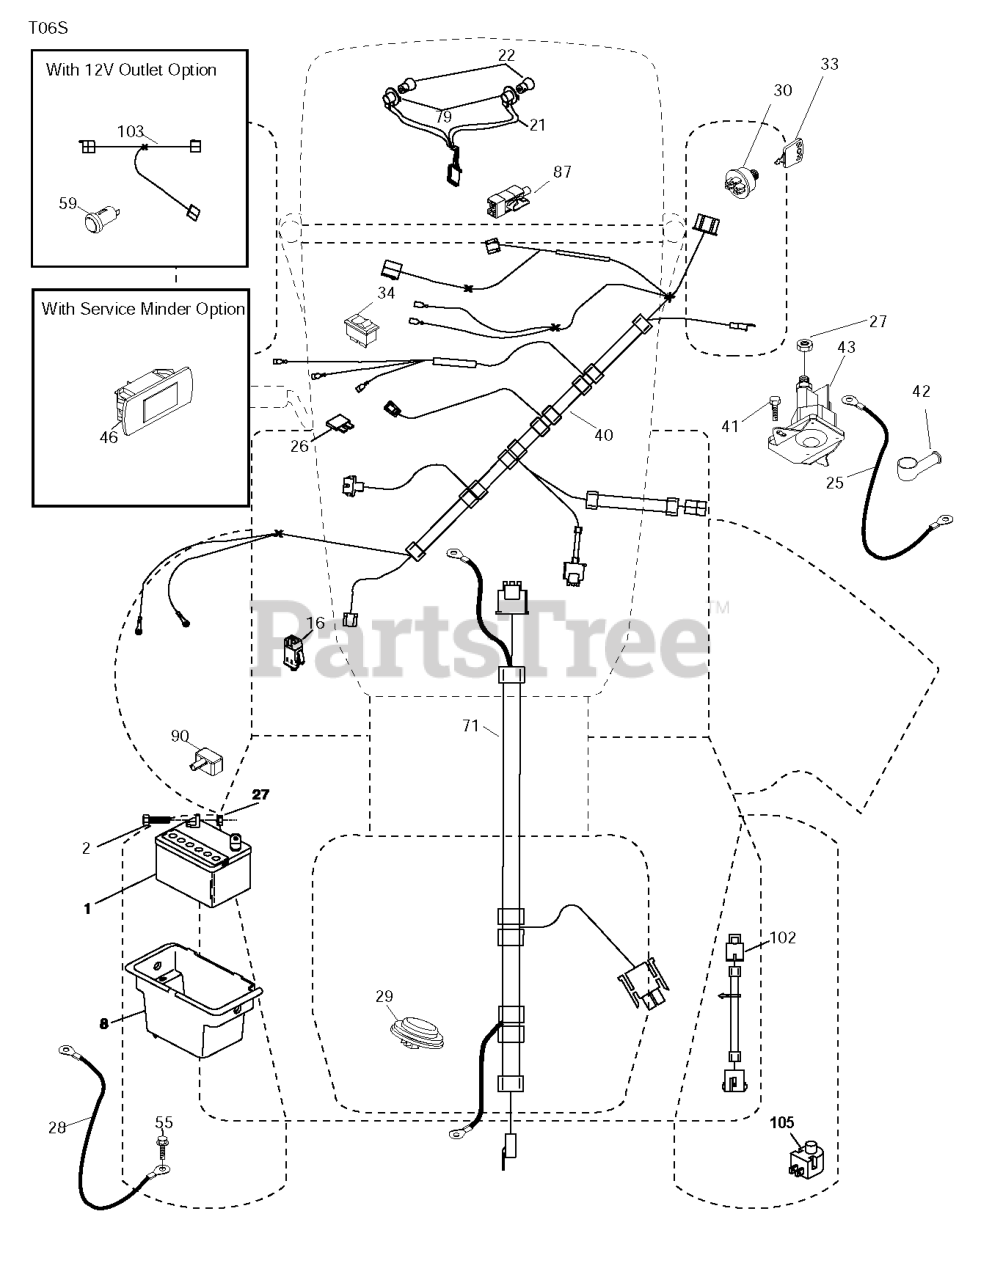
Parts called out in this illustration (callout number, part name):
1	Battery 12 Volt 25 Amp
2	BOLT.HEX.1/4.X.3/4.DICHROMATE
8	BOX.BATTERY.MNT.REAR.L
16	SWITCH INTERLOOK PUSH-IN
21	HARNESS.LIGHT W/4152J BULBS
25	CABLE.STARTER.6GA.BL/RED.14.
26	FUSE 20AMP
27	NUT
28	CABLE.BLACK.18"REAR.BA
29	SWITCH.SEAT.DELTA.OPC.
30	SWITCH.IGN.DELTA.W.LGH.ROS
33	KEY.CHAIN.BLISTER.PACK.GEN.USA
40	HARNESS IGN. DASH
41	SCREW
42	TERMINAL COVER
43	SOLENOID.W/BRASS.PLUNGER
46	RP.GUAGE.SRVCMNDR.HRMTR.
55	SCREW 5/16"
71	HARNESS.IGN.CHASS.TEX.REAR.BAT
79	BULB HOLDER ASM.
87	SWITCH.INTRLCK.CLUTCH.
90	COVER, TERMINAL BATTERY
102	HARNESS PIGTAIL PCH TEX ROS
105	REVERSE SWITCH
